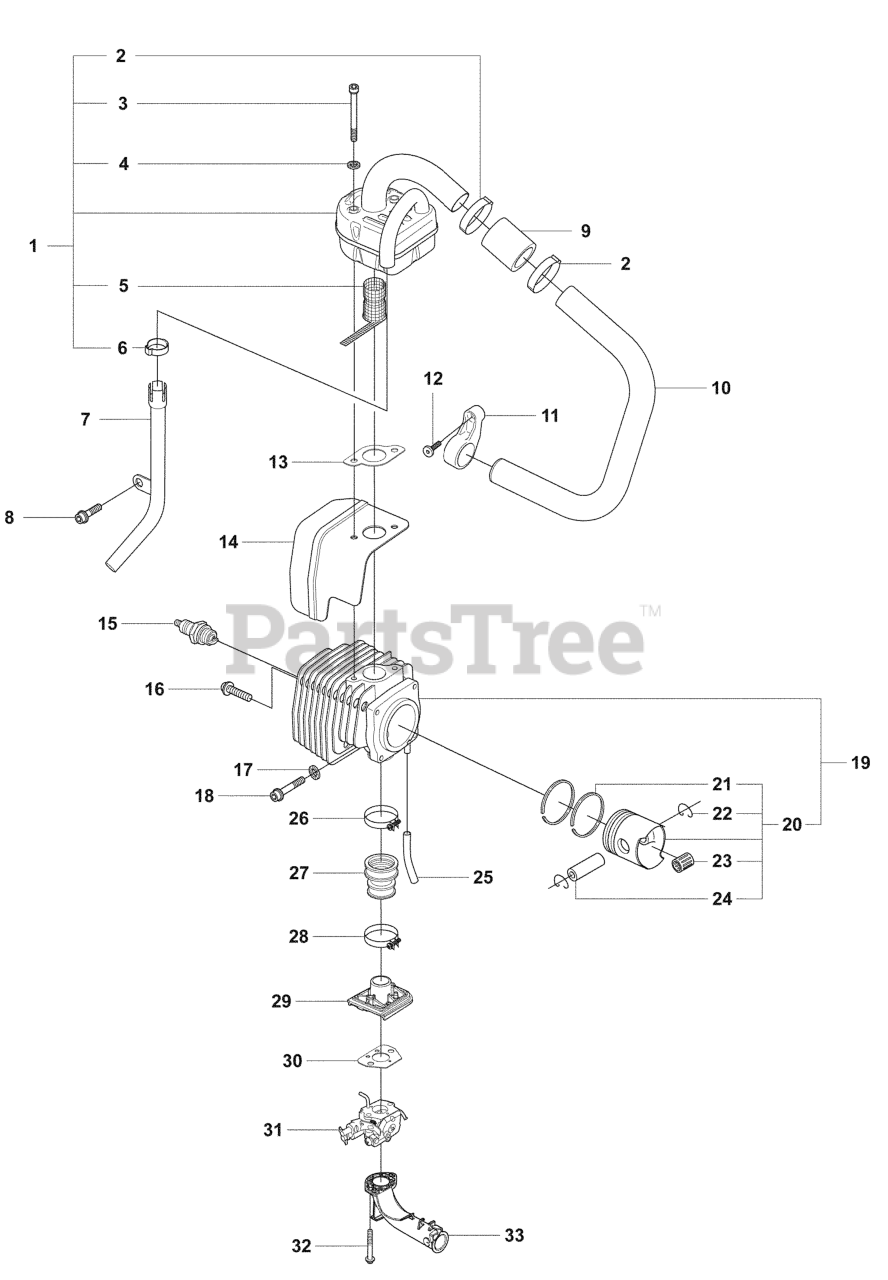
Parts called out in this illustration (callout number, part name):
4	DOUBLE WASHER
5	SPARK ARRESTOR
10	PIPE
12	SCREW M5X14
15	SPARK PLUG RCJ7Y
16	SCREW MC6S 5X25
17	DOUBLE WASHER
20	PISTON CPL 44MM
21	PISTON RING
22	WRIST PIN CLIP
23	BEARING
24	PISTON BOLT
25	FUEL HOSE
26	CLAMP
27	INLET TUBE
28	CLAMP
31	CARBURETOR
33	PIPE
33	INLET BEND 5MM WIRE
